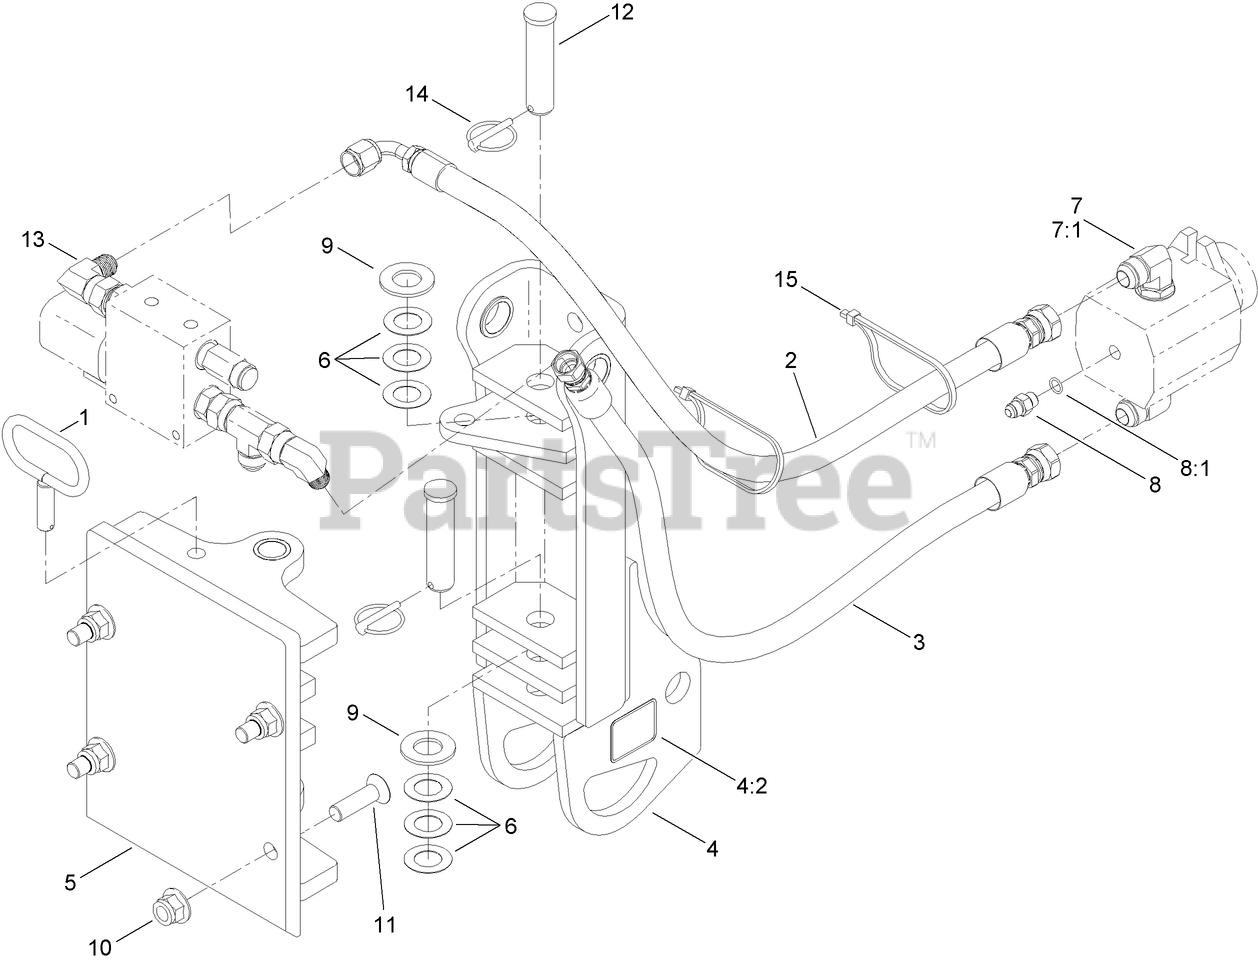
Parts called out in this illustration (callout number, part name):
1	LOCK-SWING
2	HOSE ASM
3	HOSE ASM
4	PIVOT ASM
4:2	DECAL-TIE DOWN
5	SLIDE-QUICK ATTACH
6	WASHER-FLAT
7	FITTING-ELBOW, 90 DEG
7:1	O-RING
8	FITTING-STRAIGHT
8:1	O-RING
9	WASHER-FLAT
10	NUT-HHF
11	SCREW-HSFH
12	PIN-PIVOT
13	FITTING-ELBOW, 90
14	PIN-KLIK
15	TIE-CABLE
